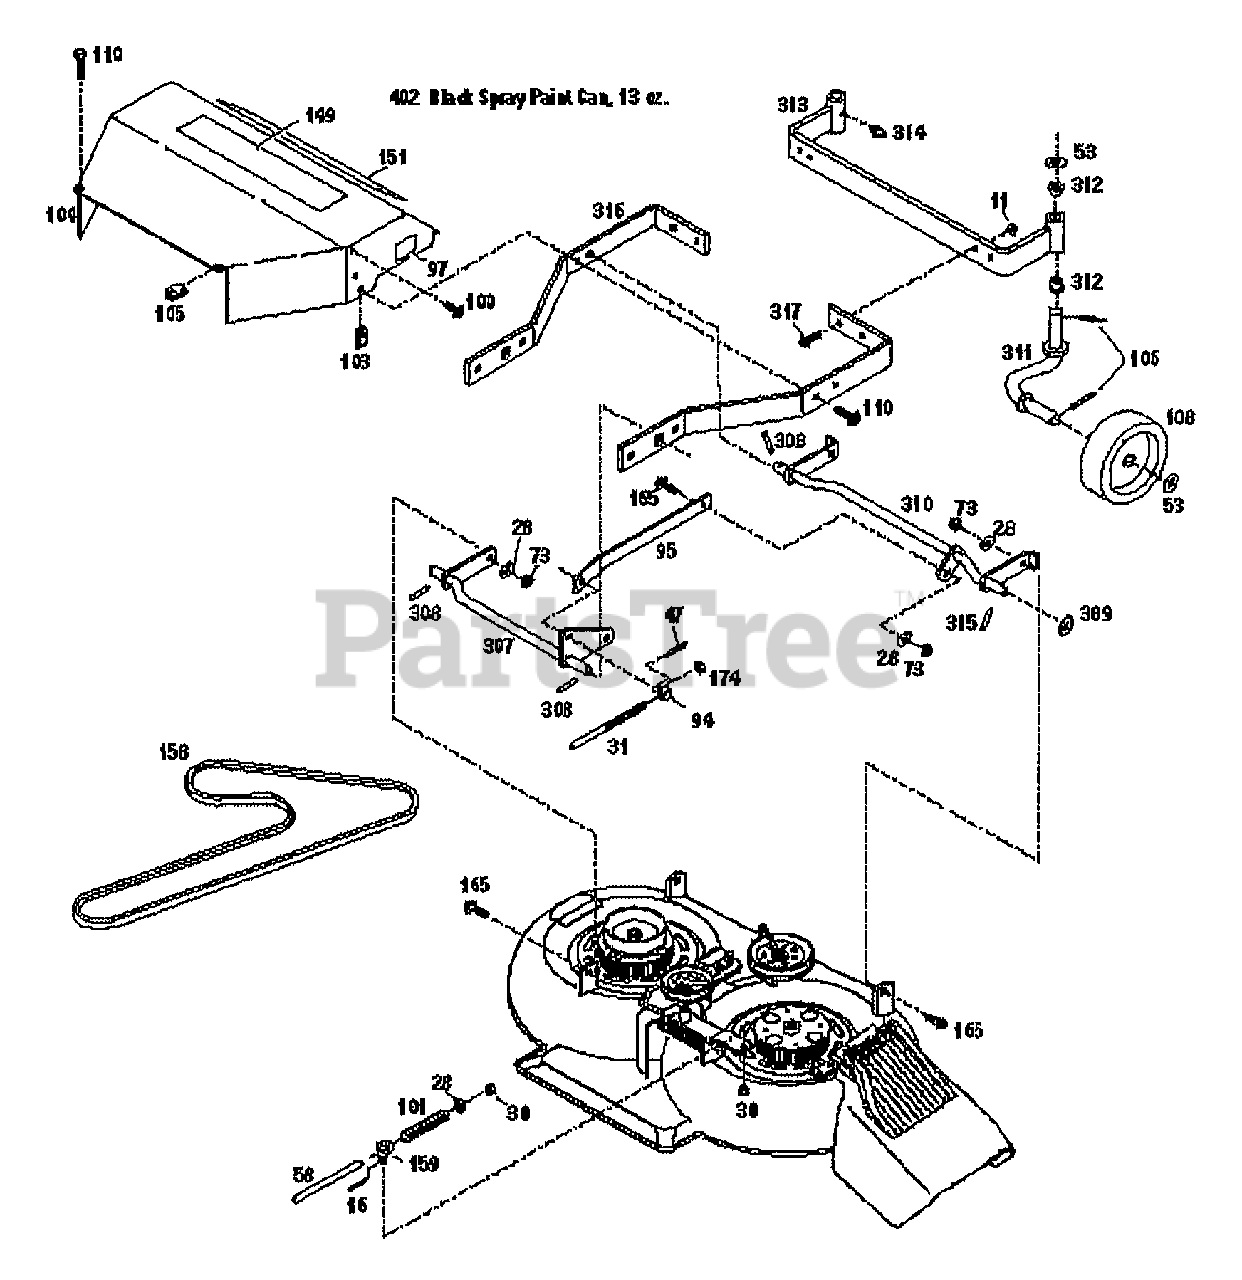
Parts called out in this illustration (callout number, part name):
11	NUT-HFLK 3/8-16 ZP
16	PIN-COTTER .093X.625
28	WASHER-FLAT 3/8 SAE
30	NUT-LOCK 3/8-16
31	ASSM-CRANK LIFT
47	PIN-COTTER .125 X .75 ZP
53	WASHER-1.25X.765X.049
58	ROD-LOWER BLADE
73	NUT-HEX/JAM 3/8-16 ZP
94	BLOCK-PIVOT ZP
95	BAR-LEVELER
97	DECAL-CUTTING HEIGHT
100	BOLT-TAP 8 X 3/8
101	SPRING-COMPRESS BLADE ROD
103	NUT 5/16-18 SPEED
104	COVER-BELT
105	NUT-SPEED
106	PIN-COTTER .125X1.5
108	GAUGE-WHEEL
110	SCR-HFLK 5/16-18X.75 ZP
149	DECAL-TROY BILT
151	DECAL-33" COMBO DECK
159	BOLT-EYE
165	SCR-SHLDR 3/8-16X.25 G5ZP
174	NUT-TOPLK .4375-14
307	ASSM-REAR LIFT
308	PIN-DRIVE .25X1.00
309	WASHER-1.305X.649X.098 ZP
310	ASSM-FRONT LIFT
311	ASSM-SPINDLE
313	SUPPORT-GAGE {34087,34087C,34342}
313	SUPPORT-GAGE FRONT {34342,34343}
314	FITTING-GREASE 1/4-28X2.00
315	PIN-DRIVE .25X3.0 ZP
315	SUPPORT-MOWER
317	SCR-HFLK 3/8-16X1.00 ZP
402	PAINT-BLACK SPRAY
